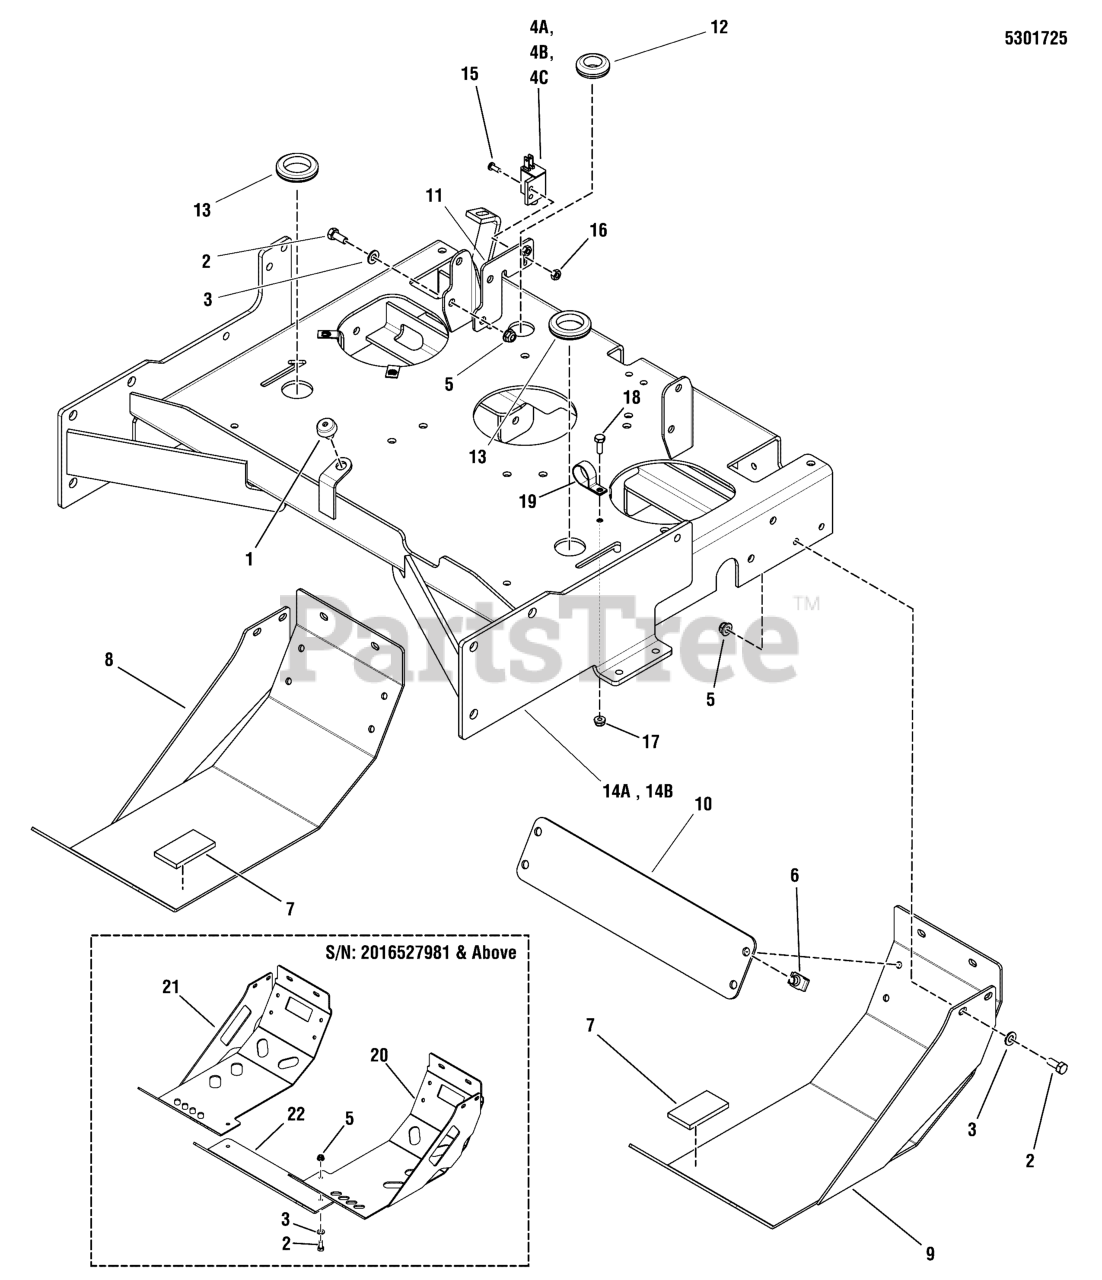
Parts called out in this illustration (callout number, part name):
1	MNT, VBRTN, RBBR
2	BOLT, 5/16-18 X 3/4 GD5
3	WASHER, 5/16" SAE
5	NUT, 5/16-18 HEX NYLOCK FLANGE
6	BODY CLIP, 5/16-18-7GA MATERIAL
7	PAD, RUBBER MOUNT, 1/4 MAT
8	WELD, SKID PLATE, RH - RED
9	WELD, SKID PLATE, LH - RED
10	PLATE, REAR GUARD, SW20-52 - RED
11	PLATE, NEUTRAL SWITCH MOUNT - RED
12	GROMMET, 7/8
13	GROMMET, 1-1/4
15	SCREW- #10-24 X 1/2 ROUND PHILLIPS
16	NUT, #10-24 HEX
17	NUT, 1/4-20 HEX NYLOCK FLANGE
18	BOLT, 1/4-20 X 3/4 GD5 YZ
19	CLAMP, VINYL INSULATED
20	WELD, SKID PLATE, LH - RED
21	WELD, SKID PLATE, RH - RED
22	PLATE, FRONT SKID - RED
